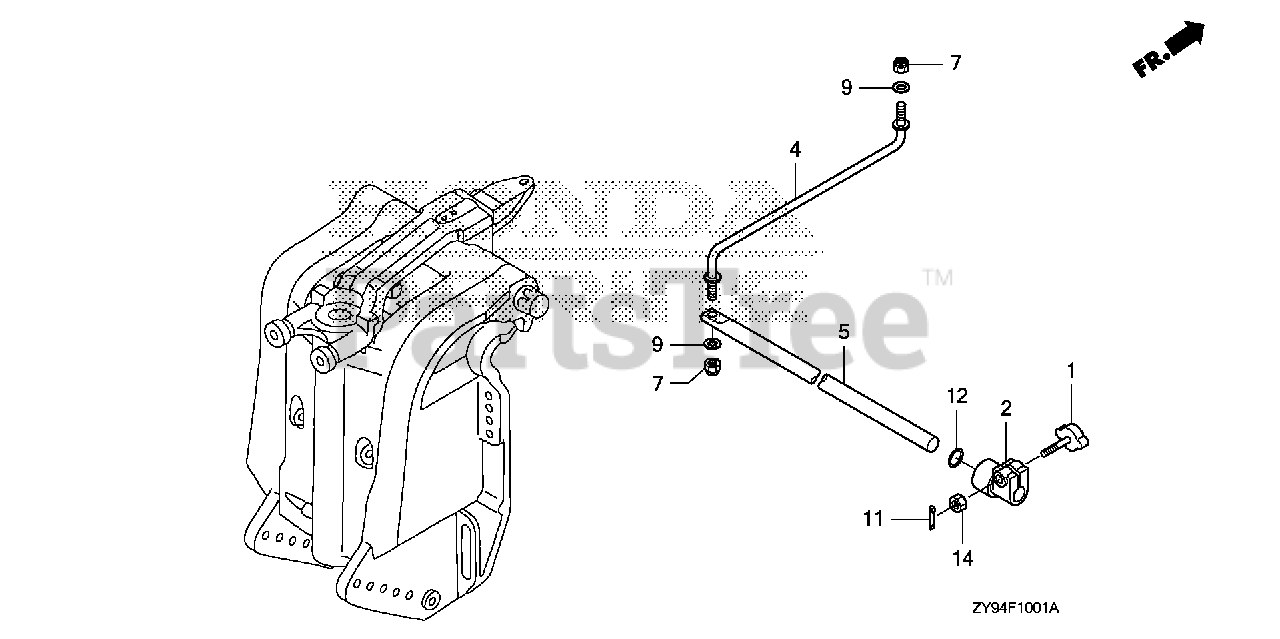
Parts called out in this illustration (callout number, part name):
1	BOLT, FRICTION
2	BLOCK, STEERING FRICTION
4	ROD, STEERING FRICTION
5	SHAFT, STEERING FRICTION
7	NUT, SELF-LOCK (8MM)
9	WASHER, PLAIN (8MM)
11	PIN, SPLIT (2.0)
12	O-RING (15.54X2.26)
14	NUT, HEX. (6MM)
